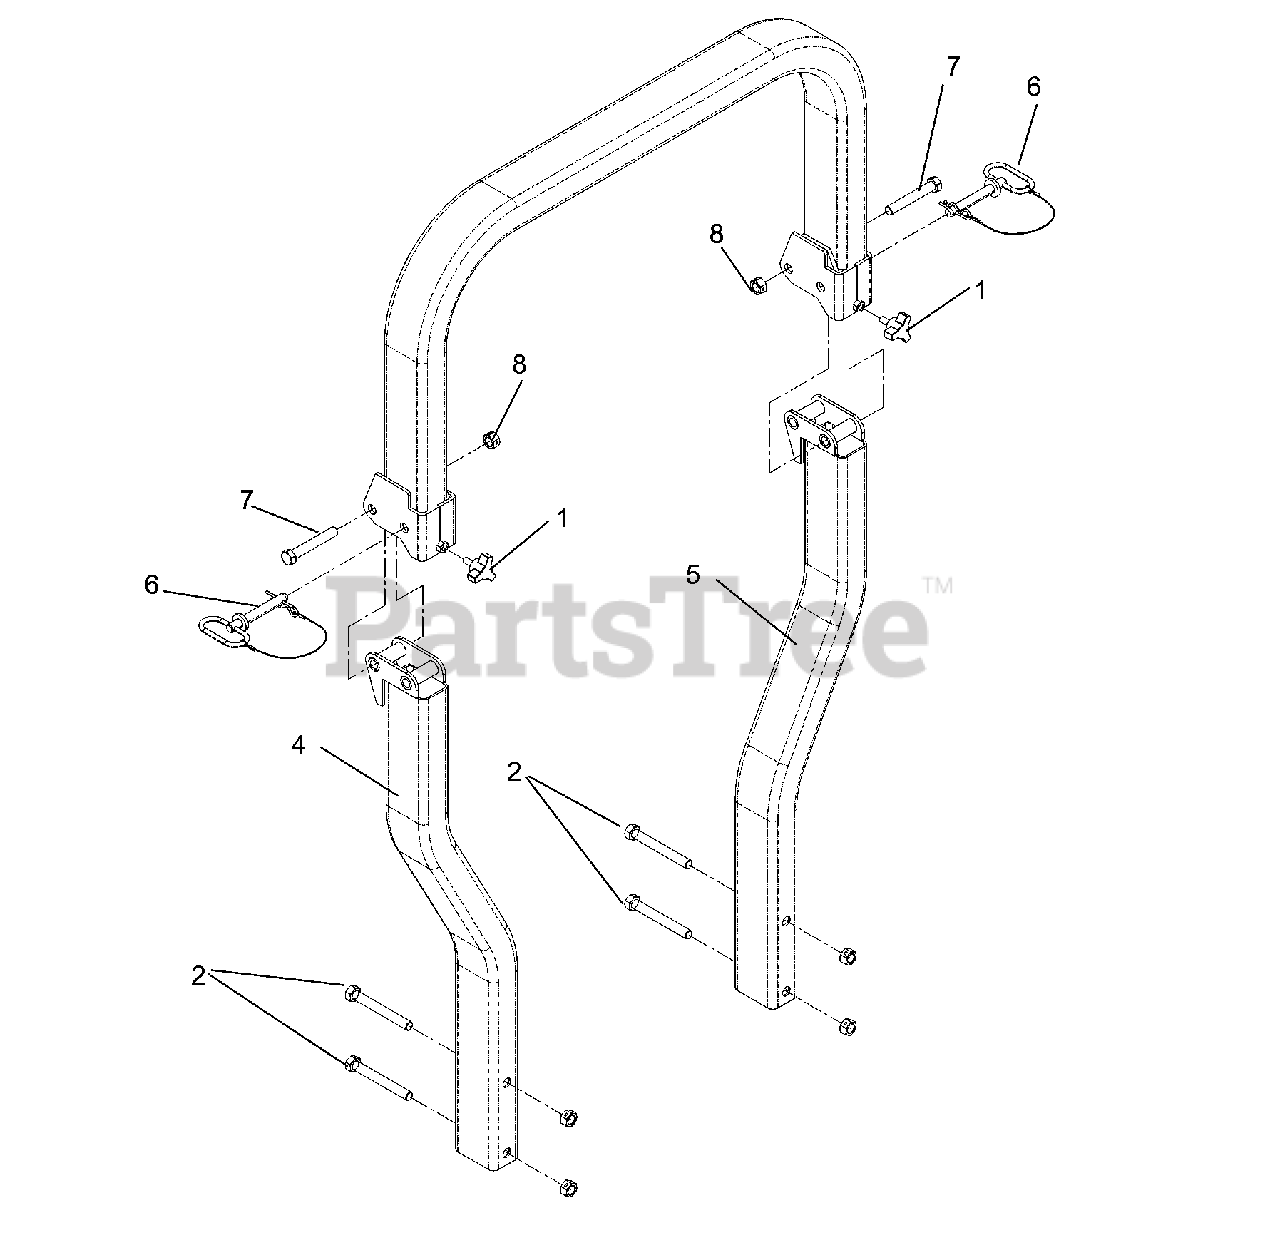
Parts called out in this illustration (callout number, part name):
1	KNOB W/STUD
2	HCS 1/2-13 X 4 GR 5 ZD
7	HCS 1/2C X 3 1/4
8	NUT 1/2-13 HEX CNTRLK GR 5 ZD
